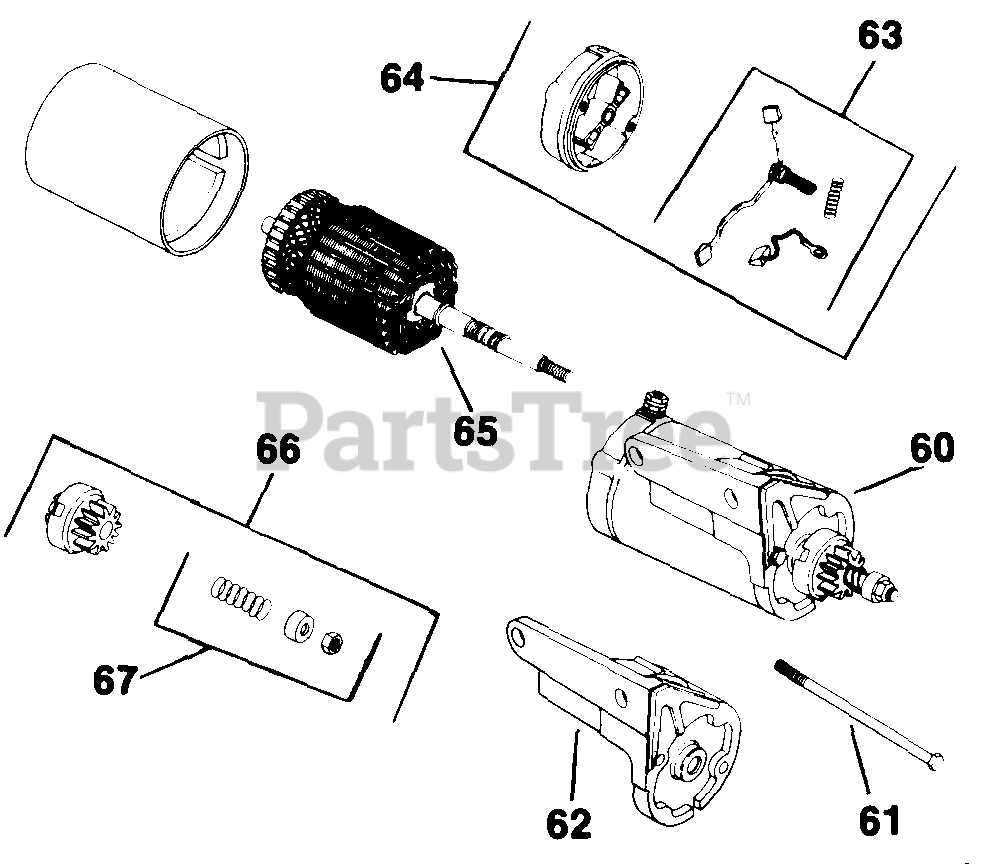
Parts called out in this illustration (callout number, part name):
60	STARTER - USE A-237511
61	SCREW - USE 12 086 02
62	BRACKET - DISCONTINUED
63	KIT - USE 52 755 15
64	CAP - DISCONTINUED
